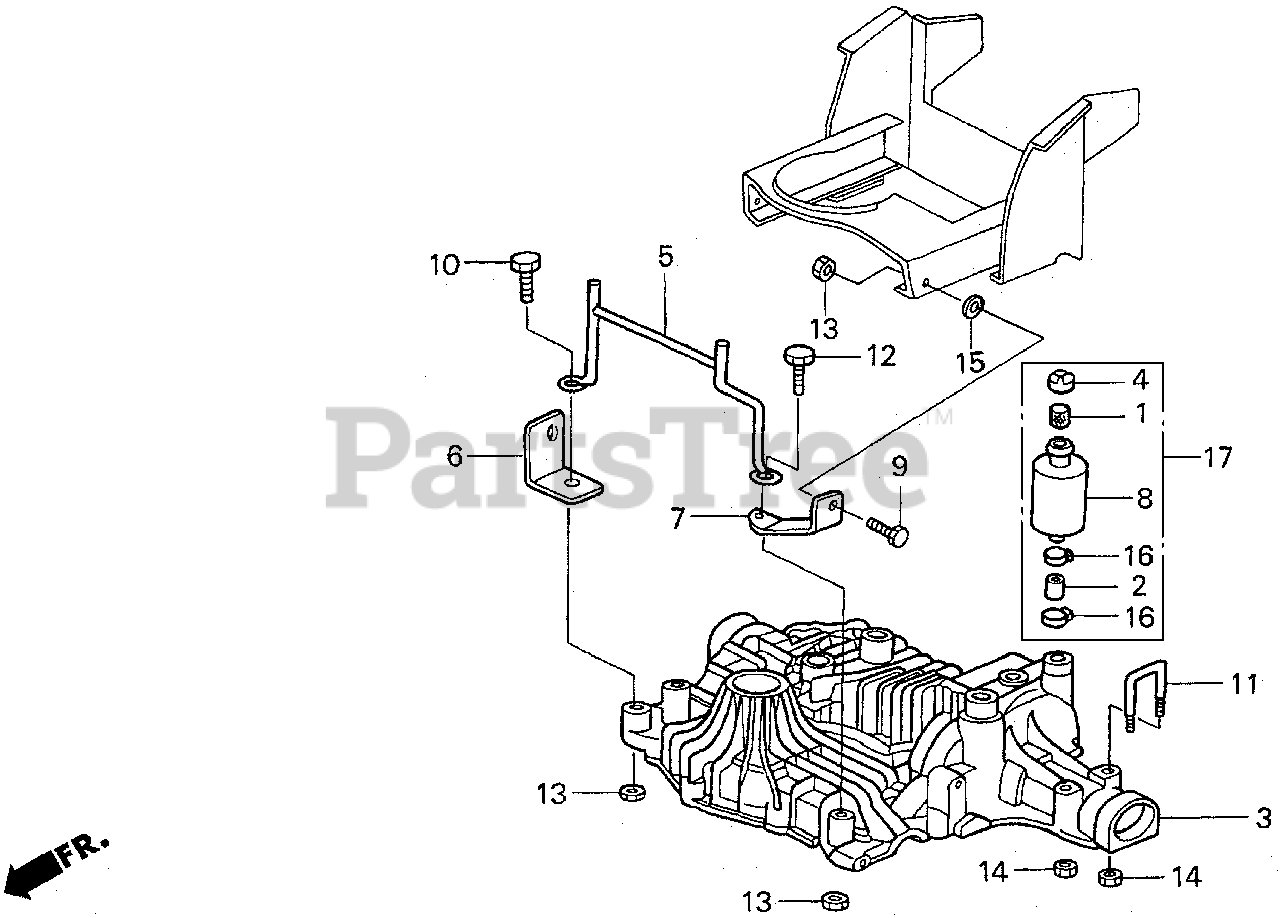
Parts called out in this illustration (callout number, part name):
1	FILTER, OIL
3	TRANSMISSION ASSY.
4	CAP ASSY., OIL
5	GUIDE, BELT
6	BRACKET A, TRANSMISSION
7	BRACKET B, TRANSMISSION
9	BOLT, HEX. (8X25)
9	BOLT, FLANGE (8X25)
10	BOLT, HEX. (8X65)
11	BOLT, U-TYPE
12	BOLT, HEX. (8X70)
13	NUT, FLANGE (8MM)
14	NUT B, LOCK (8MM)
15	WASHER, TRANSMISSION MOUNTING
16	CLIP, TRANSMISSION HOSE
17	TANK ASSY., OIL
